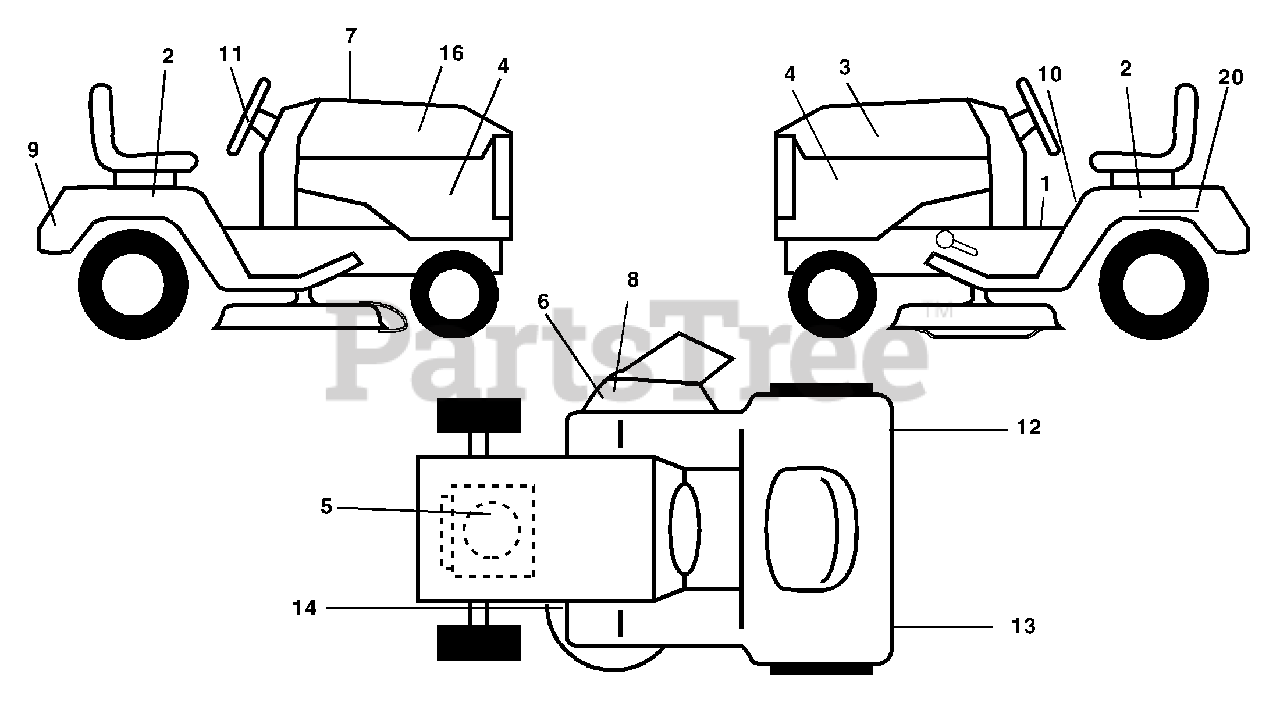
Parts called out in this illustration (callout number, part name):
1	Decal Oper
2	Decal Fender Auto
3	Decal Hood LH
4	Decal Side Panel Logo
5	Decal HP Engine
6	Decal Warning, Keep Hand Away
7	Decal Replacement Parts
8	Decal Deck "B" 42"
9	Decal Fender Logo
10	Decal Fender Danger E/F
11	Decal Ins Strg Whl
12	Decal Fend Reflector Rh
13	Decal Fend Reflector Lh
14	Decal V-Belt Schematic
16	Decal Hood Rh
20	Decal Bat Dan/Psn
